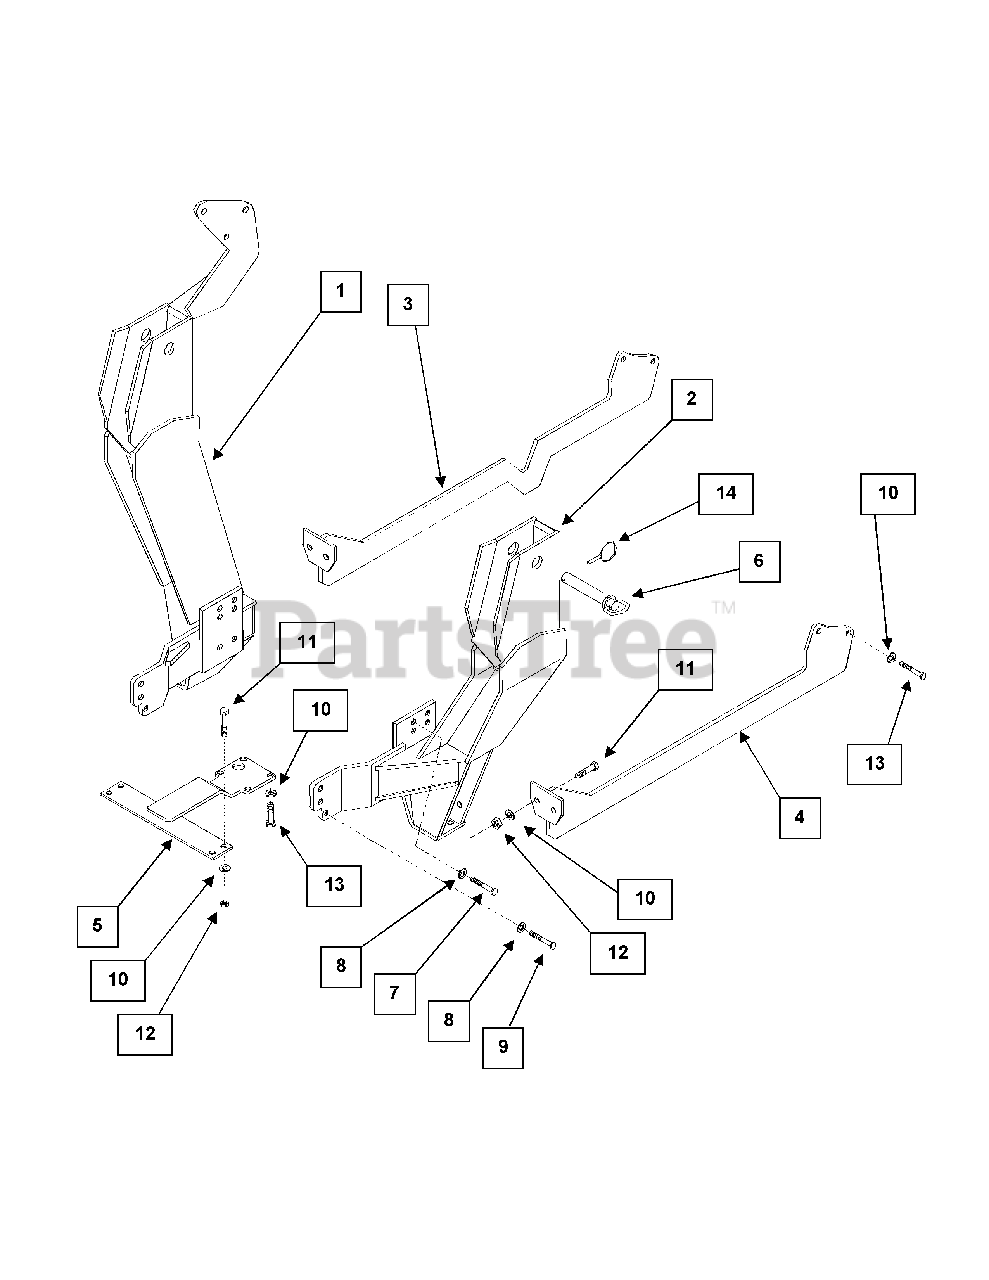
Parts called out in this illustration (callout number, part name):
1	Rear Mount Assembly, RH
2	Rear Mount Assembly, LH
3	Rear Rail Assembly, RH
4	Rear Rail Assembly, LH
5	Cross Member Assembly
7	Hex Head Cap Screw, 14mm x 35mm
8	Lock Washer, 9/16"
9	Hex Head Cap Screw, 14mm x 40mm
10	Lock Washer, 1/2"
11	Hex Head Cap Screw, 1/2" x 1 1/2"
12	Hex Head Nut, 1/2"
13	Hex Head Cap Screw, 12mm x 35mm
